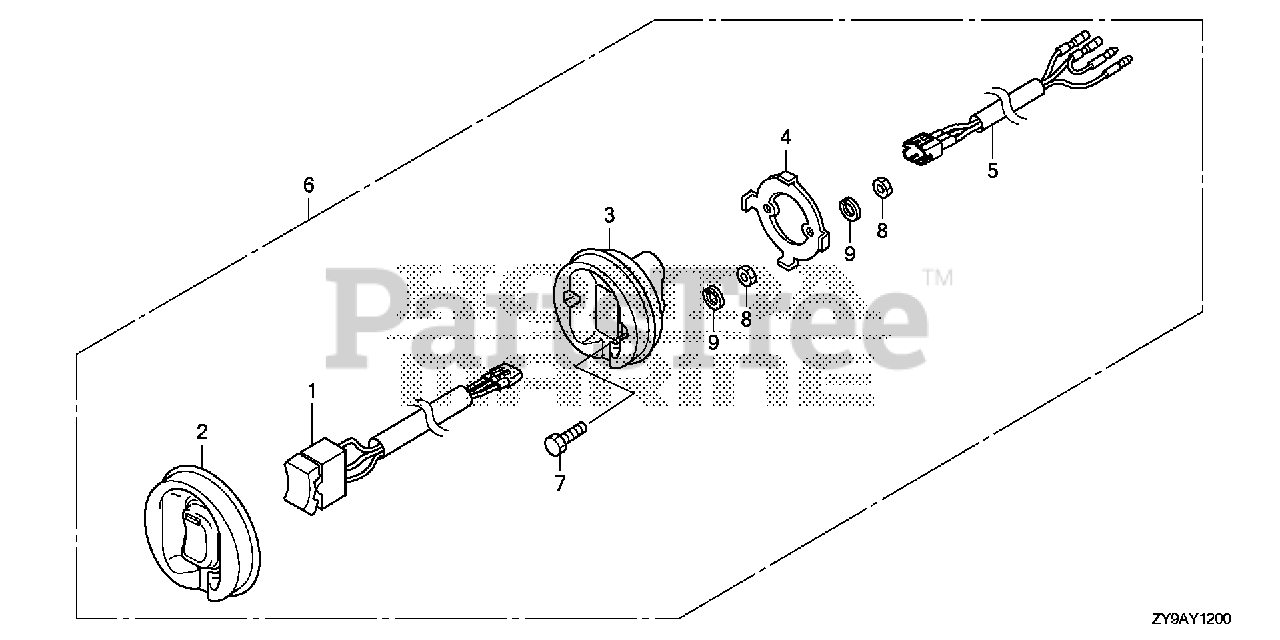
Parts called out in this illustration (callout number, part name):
1	SWITCH ASSY., TROLLING CONTROL (ENGINE NO.)
2	RUBBER, TROLLING CONTROL SWITCH PANEL (ENGINE NO.)
3	BODY, TROLLING CONTROL SWITCH PANEL (ENGINE NO.)
4	BRACKET, TROLLING CONTROL SWITCH PANEL (ENGINE NO.)
5	HARNESS, TROLLING CONTROL SWITCH PANEL (ENGINE NO.)
6	PANEL ASSY., TROLLING CONTROL (ENGINE NO.)
7	BOLT, HEX. (4X20) (ENGINE NO.)
8	NUT, HEX. (4MM) (ENGINE NO.) (NOT AVAILABLE)
9	WASHER, SPRING (4MM) (ENGINE NO.)
